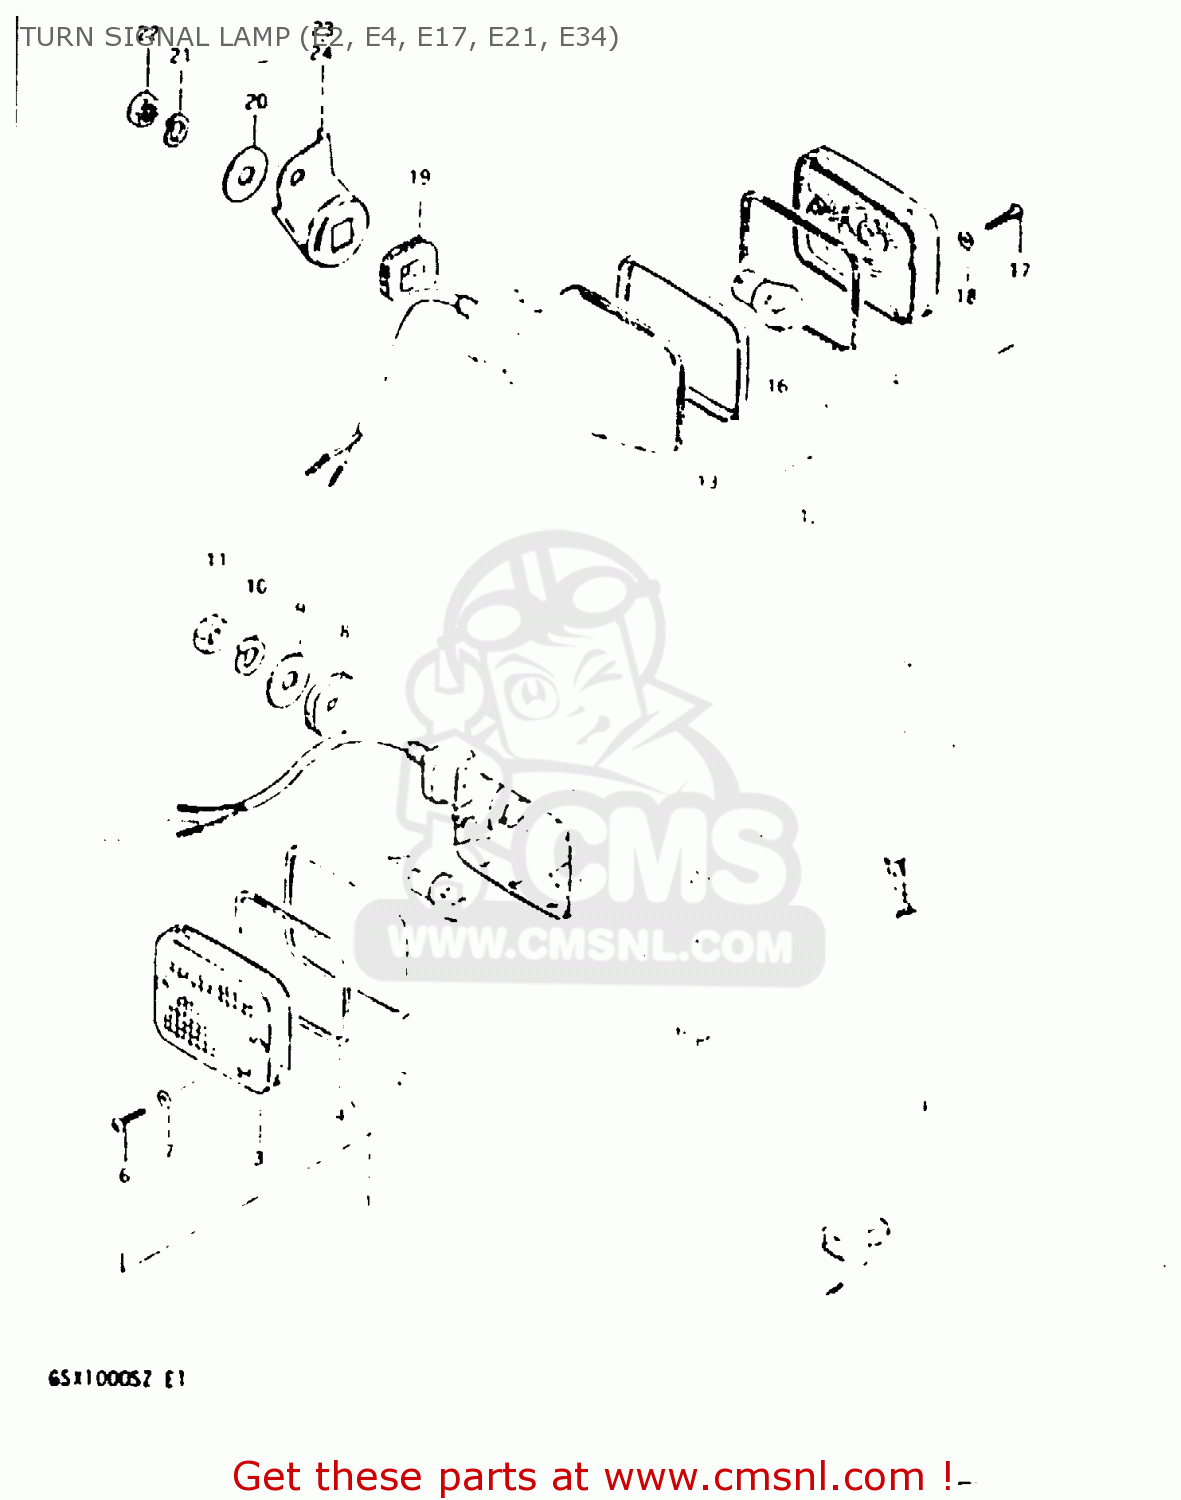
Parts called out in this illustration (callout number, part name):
1	LAMP, FRONT TURN SIGNAL
2	RIM
3	LENS
4	GASKET (NAS)
5	BULB 12V 21W
6	SCREW
7	GASKET (NAS)
8	CUSHION
9	WASHER (10.5X30X2.3)
10	LOCK WASHER
11	NUT
12	LAMP, REAR TURN SIGNAL
13	RIM
14	LENS
15	GASKET (NAS)
16	BULB 12V 21W
17	SCREW
18	GASKET (NAS)
19	CUSHION
20	WASHER (10.5X30X2.3)
21	LOCK WASHER
22	NUT
23	BRACKET,RR TURNSIGNAL LAMP,R
24	BRACKET,RR TURNSIGNAL LAMP,L
25	RELAY ASSY,TURNSIGNAL
26	UNIT,TURN SIGNAL CONTROL
